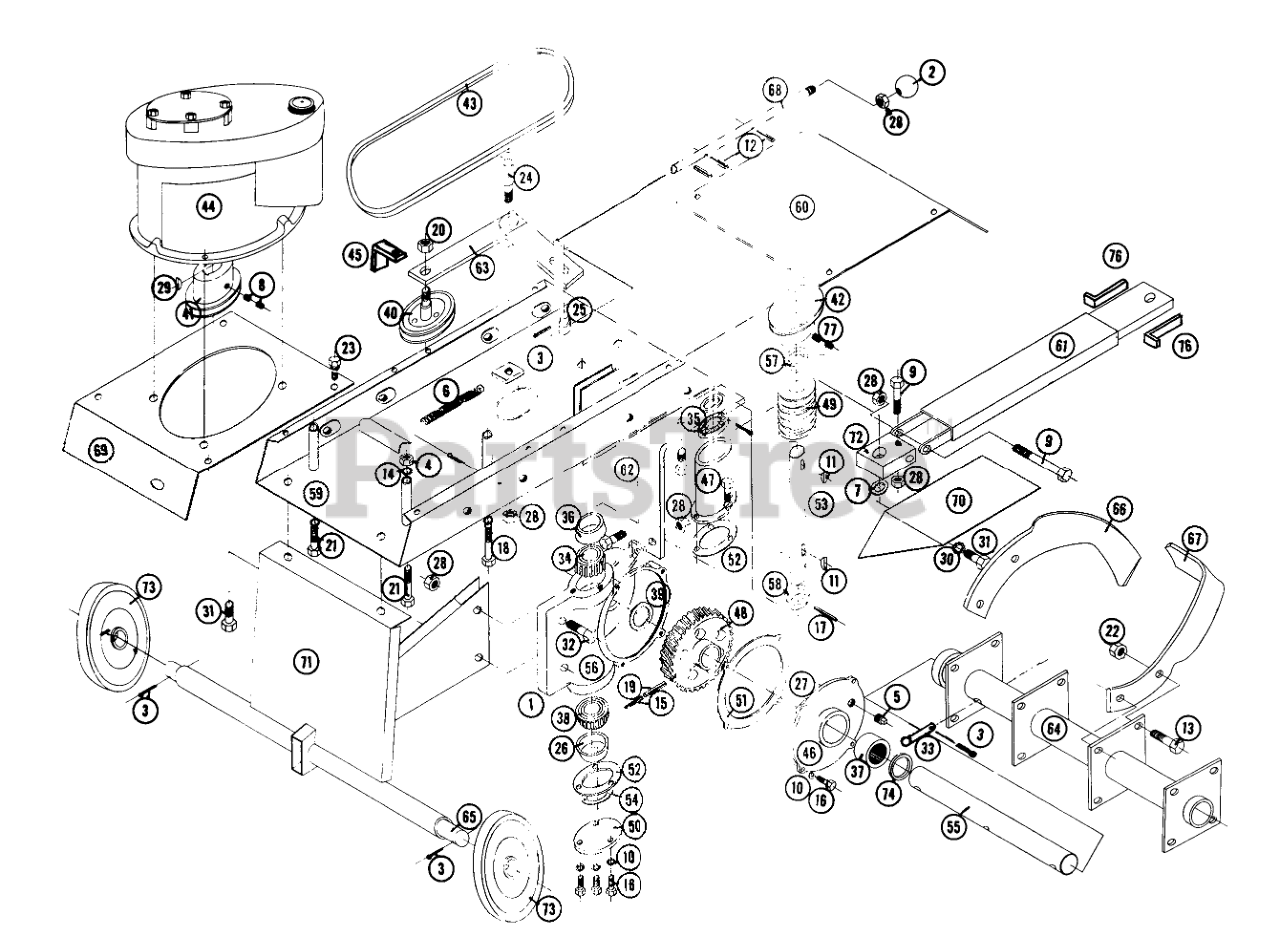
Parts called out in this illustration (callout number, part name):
1	Worm Gear Box Assembly
3	Cotter Key
4	Hex Nut
7	Washer 5/8 I.D.
8	Snap Ring
9	Cap Screw, 3/8 x 2 1/2
10	Lockwasher 1/4
13	H.H.C.S. 7/16-14 x 1 1/4 Lg.
14	Lock Washer 5/16
15	RoIl Pin
16	H.H.C.S. 1/4-20 x 5/8
17	Roll Pin
18	H.H.C.S. 5/16-18 x 3 3/4
19	Roll Pin 5/16 x 1 3/4
21	H.H.C.S. 5/16-18 x 3
22	Hex Nut 7/16-14 Lock Nut
24	Bolt-Shoulder
25	Stud
27	Shim
28	Nut
29	Woooruff Key #6
30	Lockwasher 3/8
31	Bolt 3/8-16 x 1
32	Collar w/Setscrew
34	Cone-Bearing
39	Shim
41	Engine Pulley
42	Pulley
44	Engine
46	Cover
47	Support
48	Worm Gear
49	Worm
50	Plate
51	Gasket
52	Gasket
53	Shaft-Worm
55	Shaft-Tine
56	Case
57	Spacer
59	Deck W/A
60	Top Plate
61	Hitch Bar W/A
62	Mounting Bar W/A
63	Clutch Arm W/A
64	Tine Tube W/A
65	Axle
66	Tine R.H.
67	Tine L.H.
68	Oil Seal
69	Plate-Top Rear
70	Cover-Tine
71	Pivot Tube W/A
72	Swivel Block
76	Hitch Spacer
77	Set Screw 1/4-20 x 1
